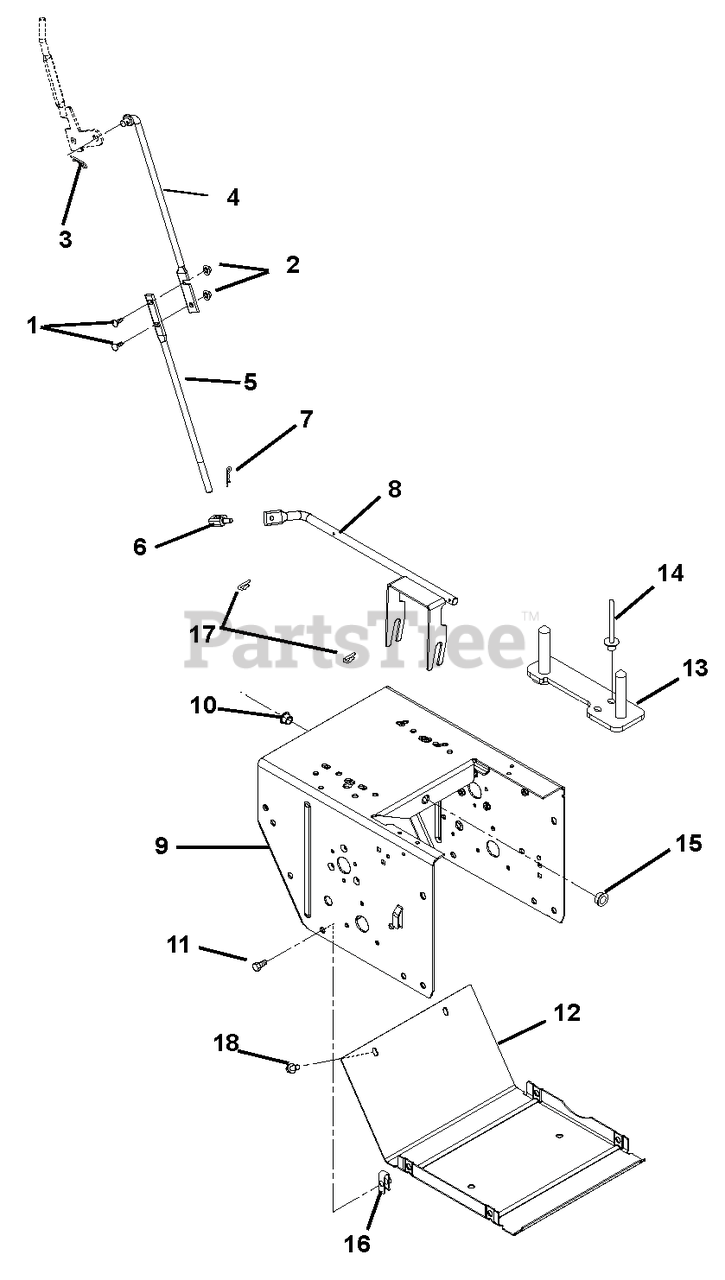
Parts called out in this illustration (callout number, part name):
1	@BLT-RDHDSQNK .25-20X.75 G5YZ
2	@NUT-LK-TOP-FLG .25-20 YWZC
3	PIN-HAIR, ENDRIES #25 YWZC
4	ROD, SHIFT-UPPER
5	ROD, SHIFT-LOWER
6	PIVOT,SHIFT ROD .375-16(TRUNN)
7	PIN-HAIR, ENDRIES #25 YWZC
8	ARM, SHIFT-WELDMENT
9	FRAME, MAIN
10	BUSHING, POLYLINER-.50 SPLIT
11	BLT-HEX .25-20X.75 HWH YZ GR5
12	COVER, BOTTOM
13	STRAP, ENGINE BOLT-WELDMENT
14	RVT-POP .187 YZ
15	BUSHING, POLYLINER-.50 SNAPIN
16	NUT-RTNR .25-20X.56
17	CLIP, SPRING
18	@SCR-TAP .25-20X.50 HWH TR YWZ
